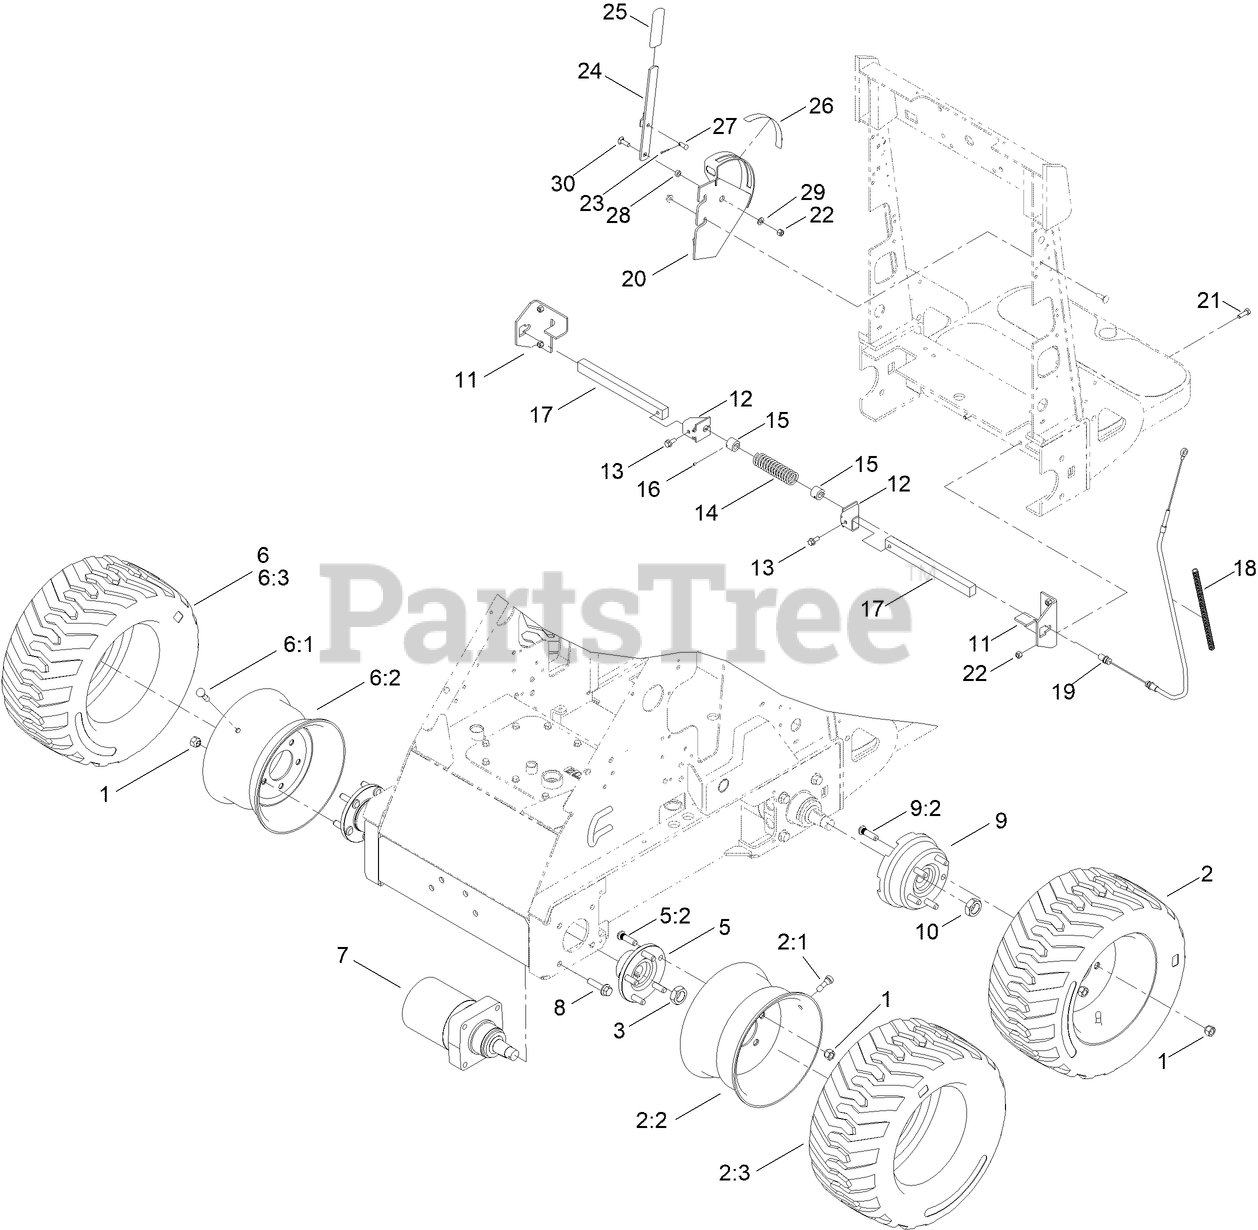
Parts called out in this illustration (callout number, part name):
1	NUT-LUG
2	TIRE AND WHEEL ASM, LH
2:2	WHEEL-10X6.00, 5 BOLT
2:3	TIRE-18X8.50-10
3	NUT-LOCK
5	HUB ASM
5:2	STUD-TYPE, DRIVE
6	TIRE AND WHEEL ASM, RH
6:2	WHEEL-10X6.00, 5 BOLT
6:3	TIRE-18X8.50-10
7	HYD MOTOR ASM
8	SCREW-HHF
9	WHEEL HUB ASM
9:2	STUD-TYPE, DRIVE
10	NUT-LOCK
11	BRACKET-BRAKE
12	BRACKET-CABLE
13	SCREW-HHF
15	TUBE-GUIDE
16	SCREW-HSH
17	BAR-BRAKE
18	TUBE-CONVOLUTED
20	PLATE-BRAKE
21	SCREW-HH
22	NUT-LOCK, NI
23	PIN-COTTER
24	LEVER-BRAKE
25	GRIP-HANDLE
26	DECAL-BRAKE
27	PIN-CLEVIS
28	HUB-LEVER
29	WASHER-PLAIN
30	SCREW-CARR
